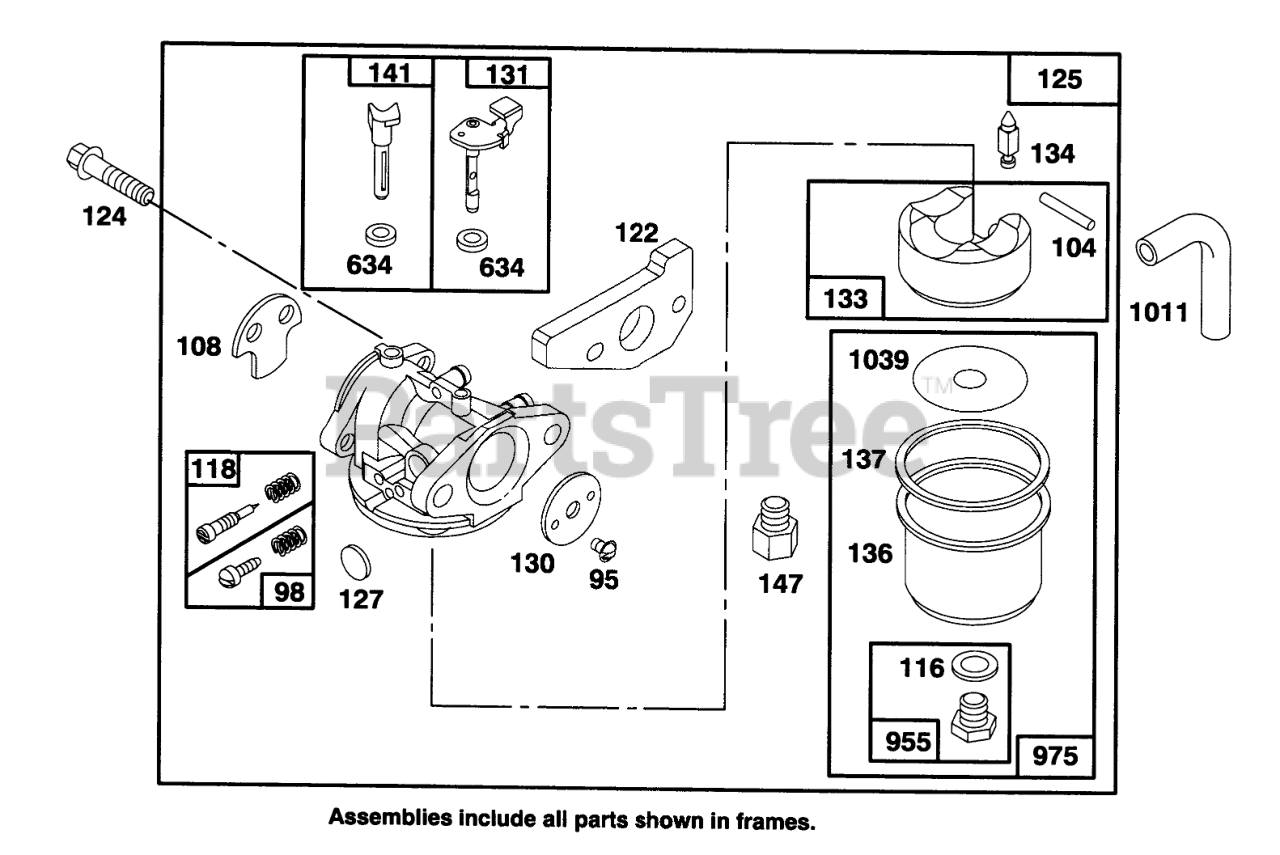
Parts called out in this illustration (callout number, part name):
8	BREATHER GASKET
95	SCREW - ROUND HEAD
98	IDLE ADJUSTING SCREW
104	FLOAT HINGE PIN
108	CHOKE VALVE
116	SEALING GASKET
116	O-Ring
118	VALVE KIT - NEEDLE
122	ADAPTER ASSEMBLY
124	HEX HEAD SCREW
125	CARBURETOR ASSEMBLY
127	PLUG
130	THROTTLE VALVE
131	THROTTLE SHAFT
133	FLOAT-CARBURETOR
134	Valve-Inlet (Includes Seat)
136	FLOAT BOWL
137	FLOAT BOWL GASKET
141	CHOKE SHAFT
147	JET ADAPTER
634	SEAL WASHER
955	HEX HEAD SCREW
975	CARBURETOR BOWL ASM
1011	VENT TUBE
1039	FLOAT LIMITER
